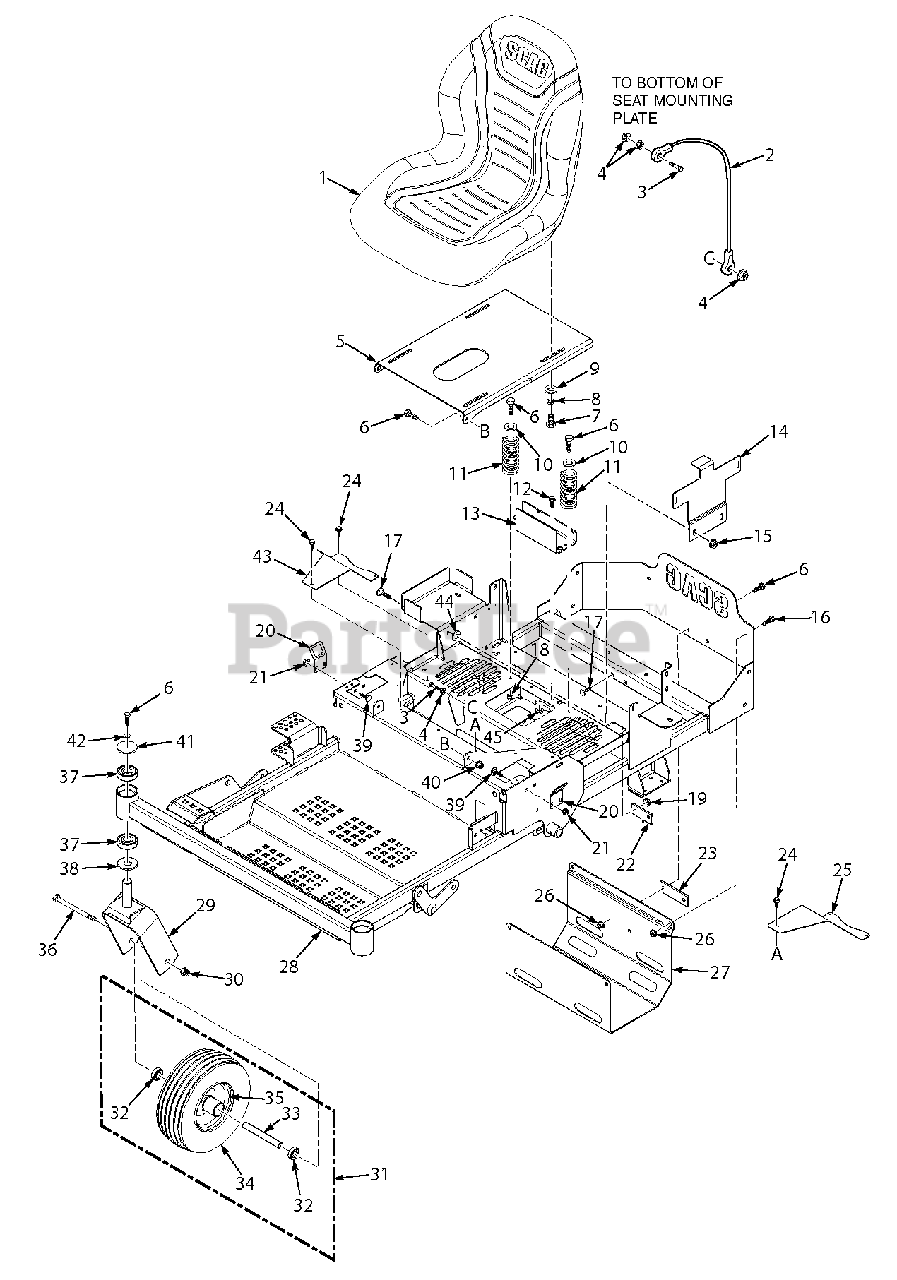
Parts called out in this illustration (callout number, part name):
1	Seat, SZL
2	Cable, Seat Stop
3	Bolt, Hex Head 1/4-20 x 1-1/4"
4	Nut, 1/4-20 Serrated Flange
5	Seat Plate w/Decal
6	Bolt, Hex Head 3/8-16 x 1"
7	Bolt, Hex Head 5/16-18 x 3/4"
8	Lockwasher, 5/16"
9	Flatwasher, 5/16-.375 x .875 x .083
10	Flatwasher, 3/8-.391 x .938 x .105
11	Spring, Seat
12	Bolt, Hex Head 5/16-18 x 3/4" Serrated Flange
13	Channel, Hose
14	Battery Hold Down
15	Nut, 5/16-18 Flange Elastic Stop
16	Bolt, Hex Head 3/8-16 x 3/4"
17	Bolt, Carriage 5/16-18 x 3/4"
18	Nut, 3/8-16 Elastic Stop
19	Nut, 5/16-18 Flange Elastic Stop
20	Bracket, Switch
21	Nut, 1/4-20 Flange Elastic Stop
22	Plate, Anti-Rotation
23	Plate, Spacer
24	Screw, #10-32 x .56
25	Guard, Belt - LH
26	Nut, 3/8-16 Serrated Flange
27	Skid Plate, SZL
28	Mainframe w/Decals - SZL
29	Yoke Weldment, Caster
30	Nut, 1/2-13 Elastic Stop
31	Caster Wheel Assembly
32	Bearing
33	Spacer, Wheel Bearing
34	Tire, 11 x 4
35	Rim Assembly
36	Bolt, Hex Head 1/2-13 x 6-1/2"
37	Bearing
38	Spacer, Yoke
39	Bolt, Carriage 1/4-20 x 3/4"
40	Nut, 3/8-16 Flange Elastic Stop
41	Flatwasher, 3/8-.406 x 2.25 x .188
42	Lockwasher, 3/8"
43	Guard, Belt - RH
44	U-Nut, 5/16 Push-On
45	Nut, 5/16-18 Serrated Flange
